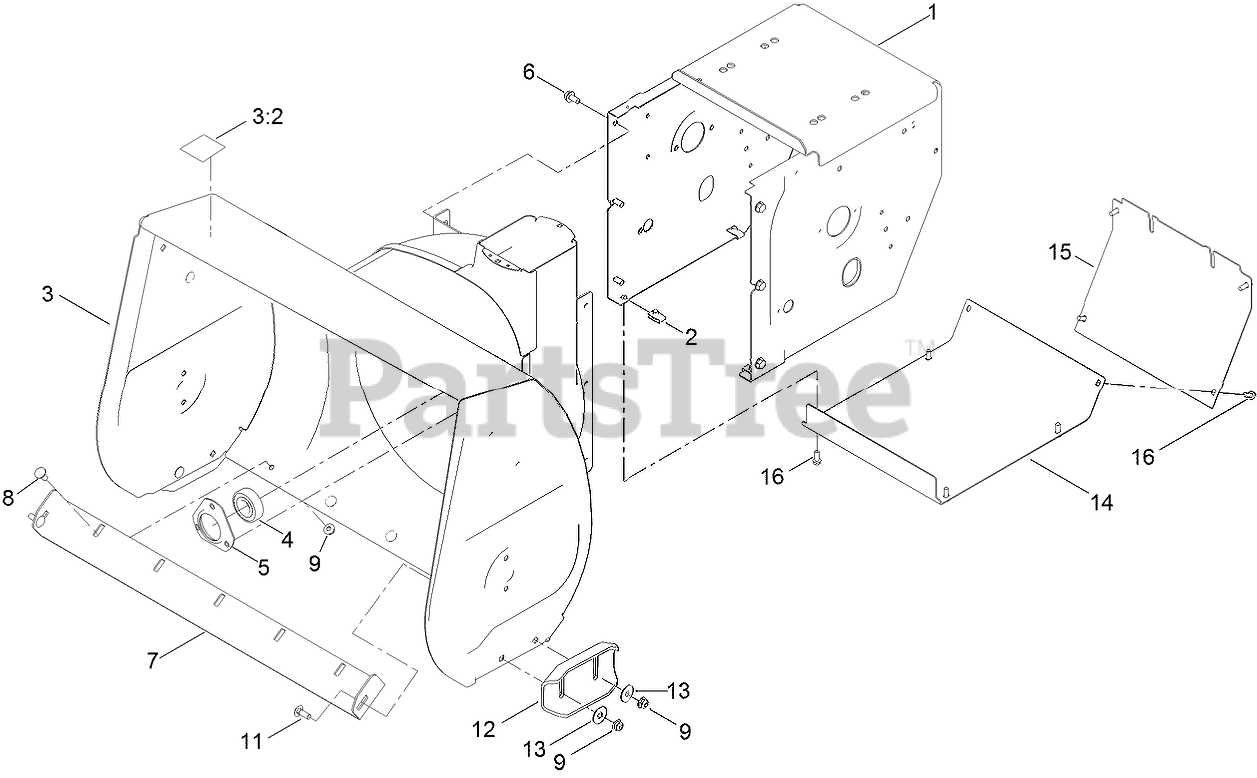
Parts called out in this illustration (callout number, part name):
1	FRAME-TRACTION
3	AUGER HOUSING ASM
3:2	DECAL-DANGER
4	BEARING-BALL
5	RETAINER-BEARING
6	SCREW-HWHTF
7	BLADE-SCRAPER
8	BOLT-CARR
9	NUT-HF
11	BOLT-CARR
13	WASHER-FLAT
14	COVER-BOTTOM
15	COVER-REAR
16	SCREW-HWH
